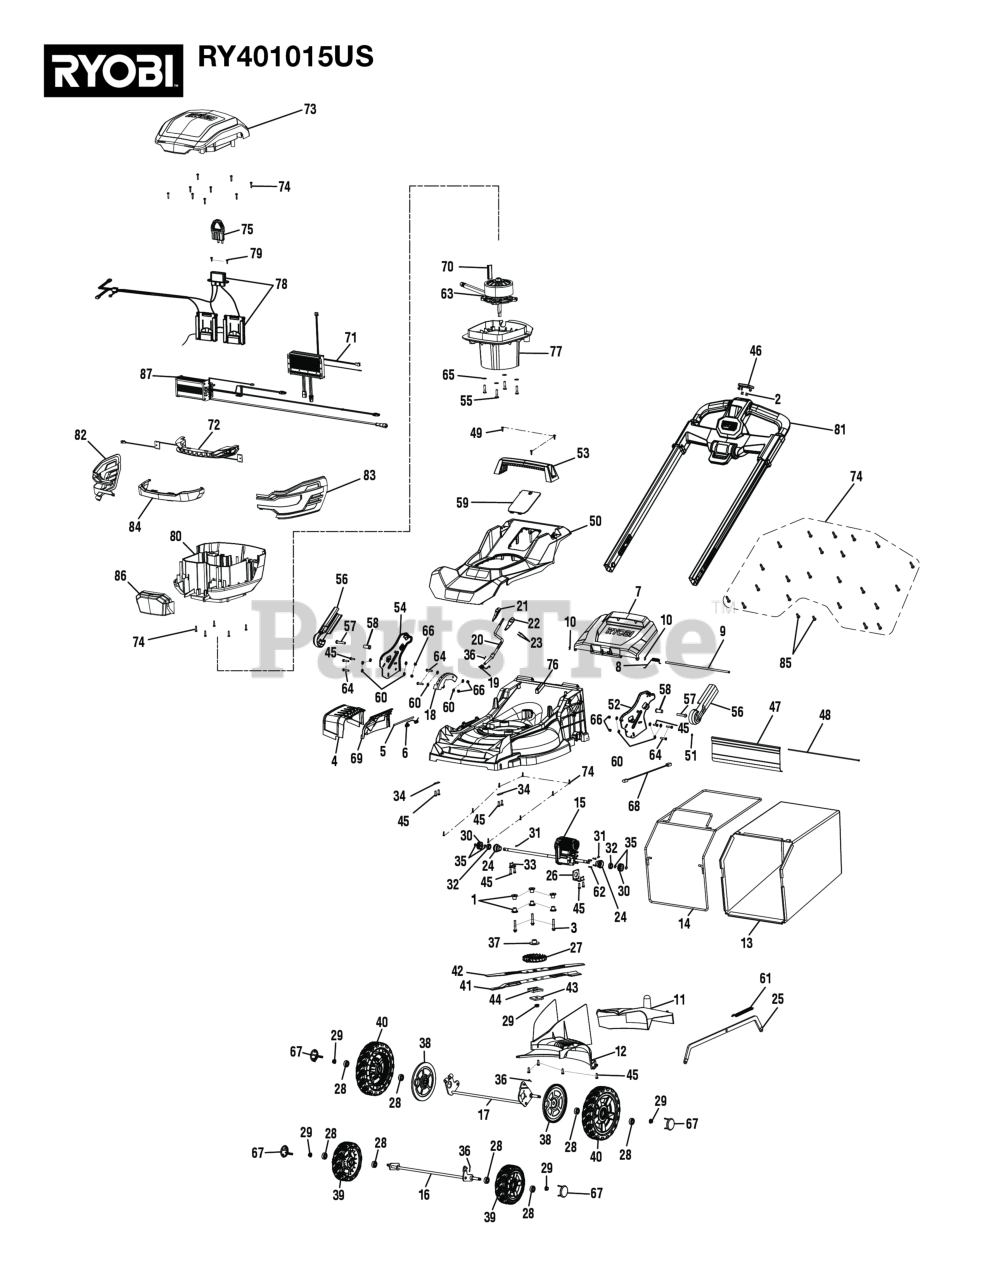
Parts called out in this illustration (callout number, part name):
1	Engine Spacer
3	Screw (M8 x 50 mm, Hex Hd.)
4	Side Charge Deflector
5	Hinge Rod
6	Mulch Cover Spring
7	Rear Door
8	Rear Door Torsion Spring
9	Rear Door Axle
10	Retaining Ring (E)
11	Mulching Plug
12	Discharge Baffle
13	Grass Bag
14	Grass Bag Frame
15	Transmission
16	Front Axle
17	Rear Axle
18	Height Adjustment Bracket
19	Torsion Spring
20	Height Adjustment
21	Height Adjustment Knob (Right)
22	Height Adjustment Knob (Left)
23	Screw (M3 x 12 mm, Pan Hd.)
24	Transmission Bearing Bushing
26	Connecting Plate
27	Motor Fan Blade Adapter
28	Ball Bearing (ID12 x OD32 x 10 mm)
29	Blade Nut (M10 x 1.25, Hex Flange Hd.)
30	Drive Gear
31	Gear Shaft
32	Ball Bearing (OD28.6 x ID12.7 x 8)
33	Rear Axle Press Plate
34	Front Axle Press Plate
35	Retaining Ring
36	Cotter PinÏ? (2.5)
37	Motor Shaft Bushing
38	Wheel Cover
39	8 in. Wheel Assembly
40	11 in. Wheel Assembly
42	21 in. Top Blade, Stepped
43	Blade Spacer Metal Plate
44	Plastic Blade Spacer
45	Screw (1/4-15 x 3/4 in., T30 Torx Pan Hd.)
46	Blade Button
47	Trailing Shield
48	Trailing Shield Pin
49	Screw (10-14 x 19 mm, T25 Torx Truss Pan Hd. T.F.)
50	Top Cover w/Labels
51	Retaining Ring
52	Handle Bracket (Left)
54	Handle Bracket (Right)
55	Bolt (M6 x 26 mm, Hex Hd.)
56	Hinge Cover
57	Screw (M10 x 48 mm, Hex. Recess Hd.)
58	Handle Bushing
59	Top Cover Door
60	Washer (1/4 in.)
61	Compression Spring
62	Screw (M5 x 14.5 mm)
64	Screw (1/4-20UNC X 31.75 in., T30 Torx Pan Hd.)
65	Washer (ID6.2 x OD15 x 0.08t)
66	Lock Nut (1/4-20 in.)
67	Wheel Hub Cap
68	Inner Wire with Connector Between Transmission and Circuit Board Assembly
69	Side Discharge Door
70	Wire Harness Cover
71	Cutting Controller Assembly
72	LED Circuit Board Assembly
73	Battery Cover Assembly (Inc. Labels)
74	Screw (M4 x 18 mm, T20 Torx Pan Hd.)
75	Start Key Assembly
76	Deck Assembly (Inc. Labels)
77	Motor Bucket
78	Key Base and Battery Foot Assembly
79	Screw (M4.2 x 12 mm, T20 Torx Pan Hd.)
80	Battery Housing Bottom
81	Handle Assembly
82	Battery Housing Front Vents (Right)
83	Battery Housing Front Vents (Left)
84	LED Clear Window Lens
85	Screw (M4 x 10 mm, T20 Torx Pan Hd.)
86	Battery Housing Front Plug Cover
87	Control Board Assembly
